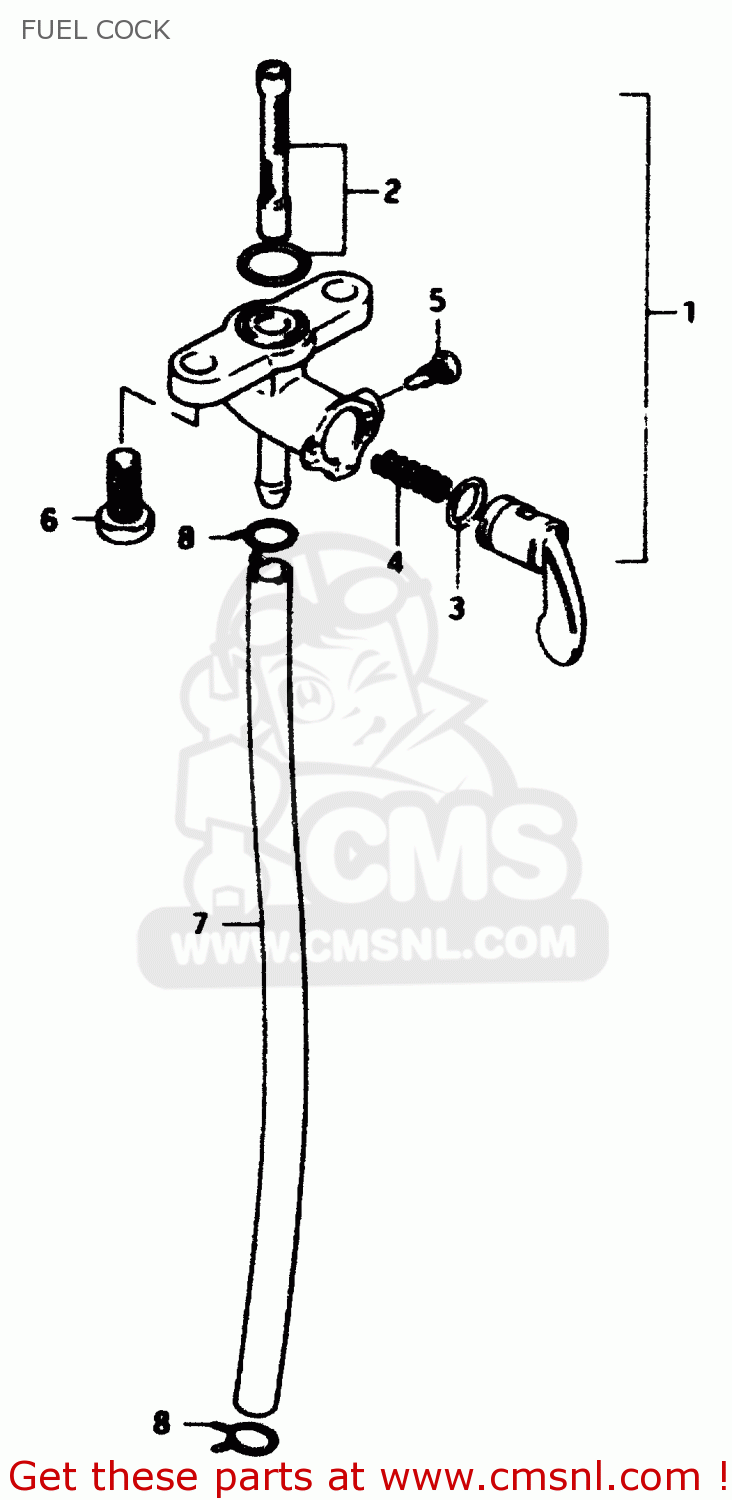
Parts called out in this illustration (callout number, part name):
1	COCK ASSY,FUEL
2	FILTER SET FUEL
3	O RING,LEVER
4	SPRING,FUEL COCK VALUE
5	SCREW
6	SCREW
7	HOSE(5X8.2X600)
8	CLIP
